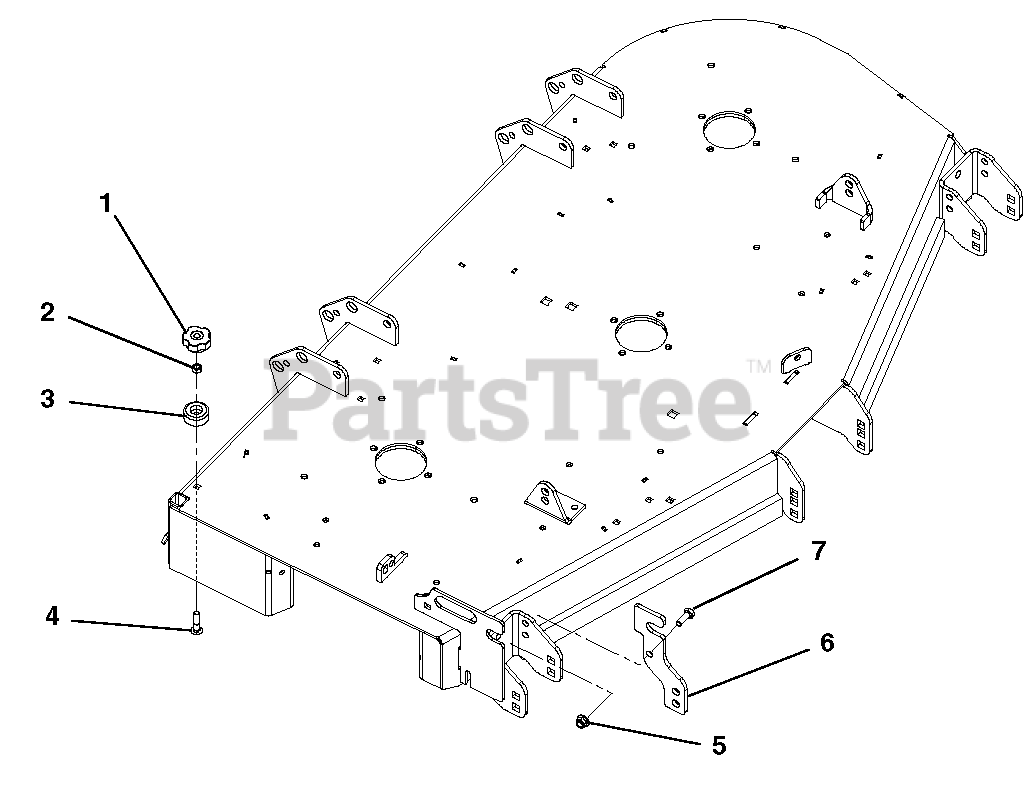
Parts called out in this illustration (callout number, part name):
1	Knob, Clamping, .312-18 Nyloc
2	Nut, Locking-Center .31-18
3	Bumper, Recessed 1.50 x .63 w/.31 Thru Hole
4	Bolt, Round Head Square Neck .31-18 x 1.50
5	Nut, .38-16 Nyloc Flange
6	Chute Storage Bracket
7	Bolt, Hex .38-16 x 1.00 Grade 5
